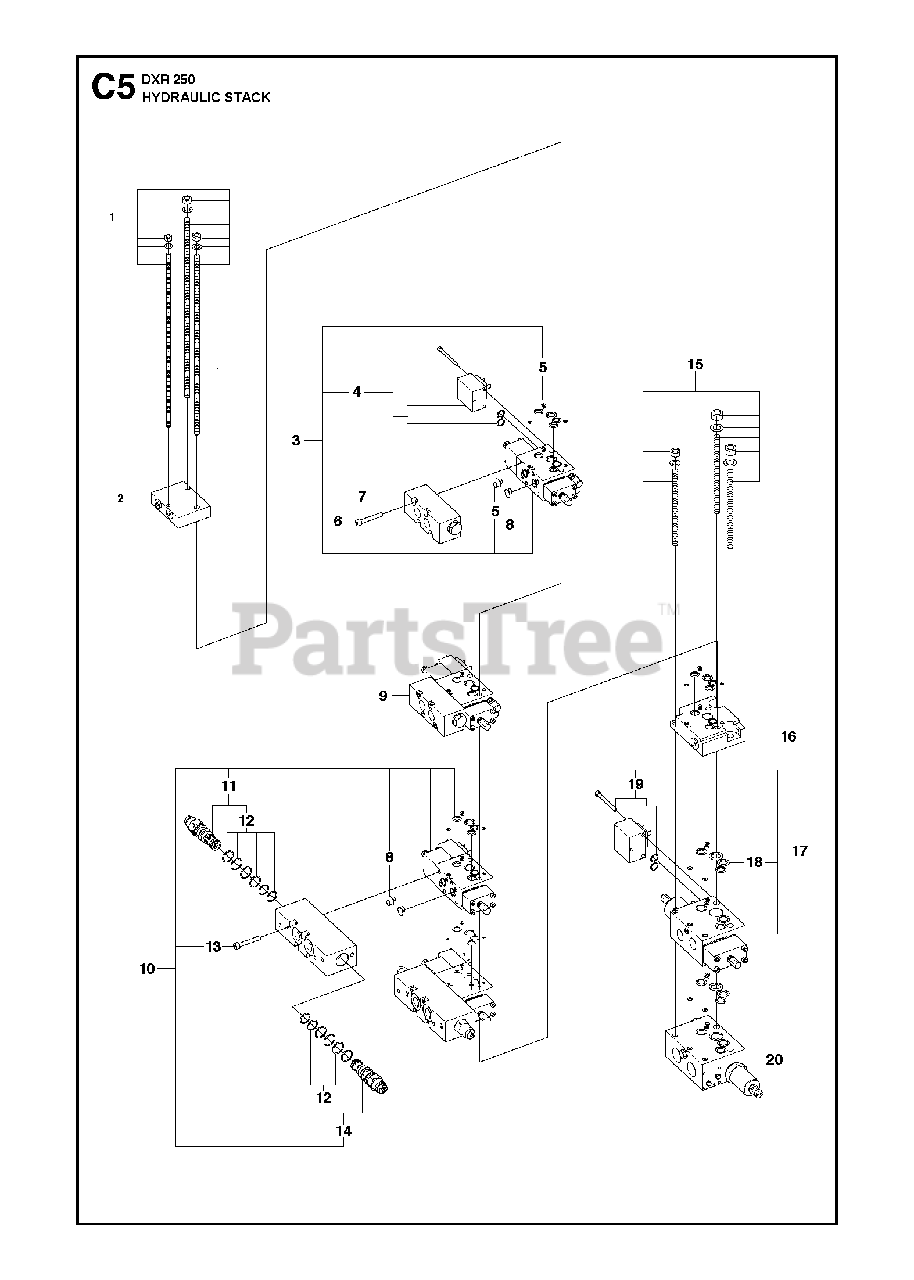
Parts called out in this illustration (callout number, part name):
1	TAPExtra hydraul function 1 (5 sections)
1	TAPExtra hydraul function 2 (6 sections)
13	SCREW IHSCM
